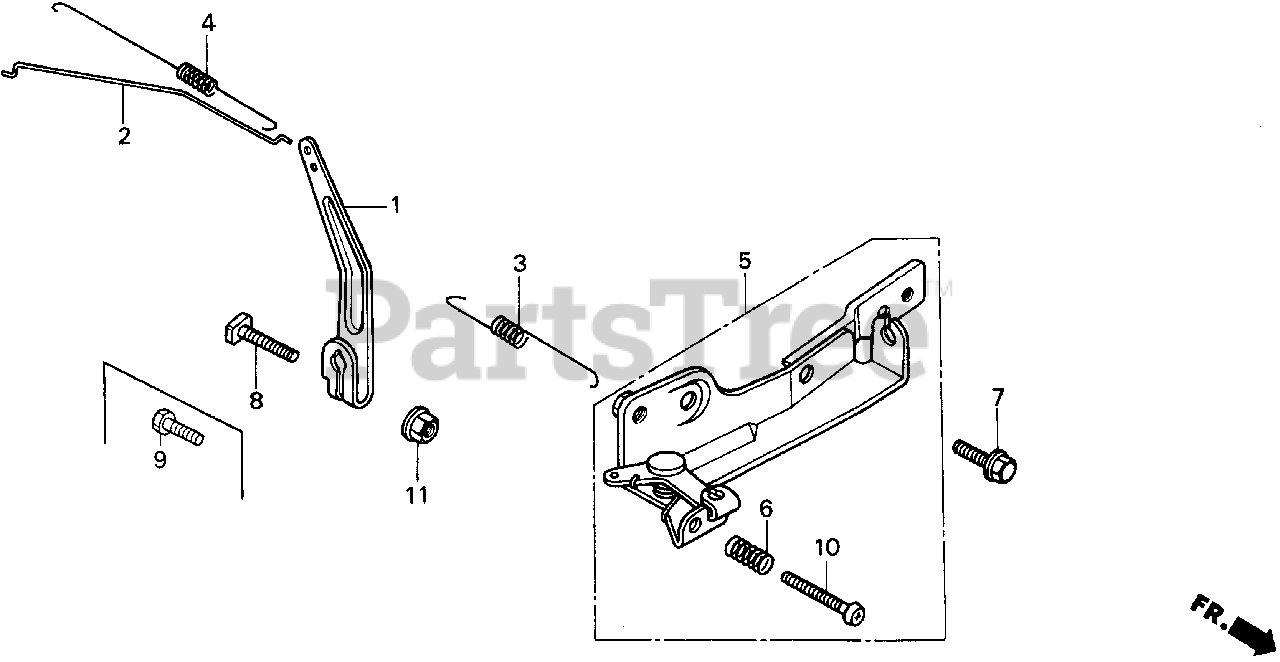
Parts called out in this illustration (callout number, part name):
1	ARM, GOVERNOR
2	ROD, GOVERNOR
3	SPRING, GOVERNOR
4	SPRING, THROTTLE RETURN
5	CONTROL ASSY.
6	SPRING, CONTROL ADJUSTING Use from Engine SN 2327377.
7	BOLT, FLANGE (6X12) (CT200)
8	BOLT, GOVERNOR ARM
10	SCREW, PAN (5X32)
11	NUT, FLANGE (6MM)
